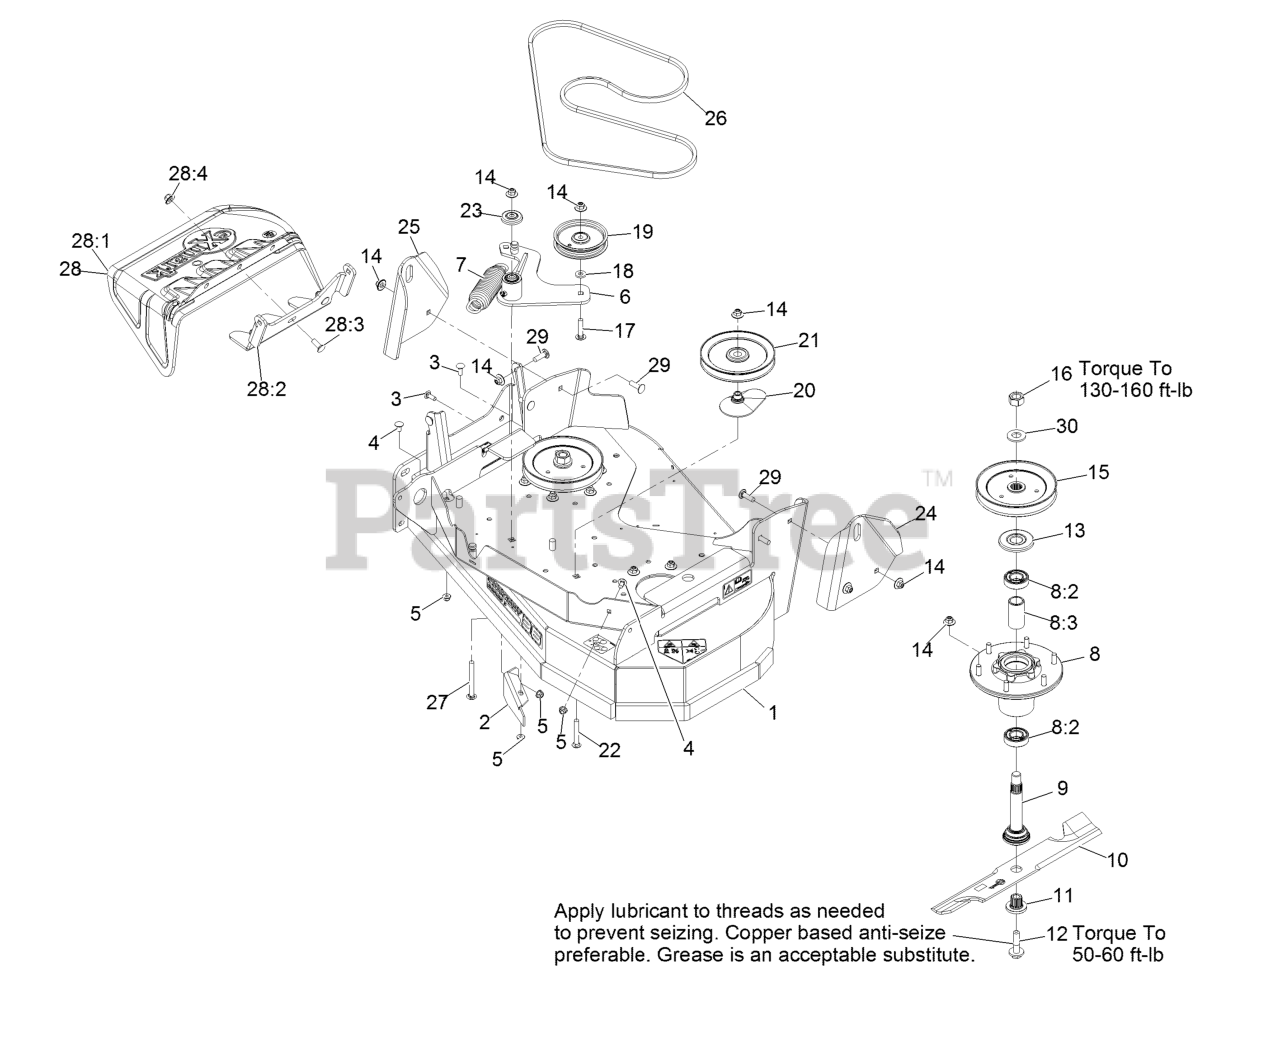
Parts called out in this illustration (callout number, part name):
1	Deck ASM - 36
2	Baffle-Dogleg
3	Bolt-Carriage 5/16-18 X 7/8
4	Bolt-Carriage 5/16-18 X 5/8
5	Nut-Nyloc 5/16-18 Flg
6	Idler Arm ASM -
7	Spring-Extension
8	ASM-Cutter Hsg With Bearings
8:2	Bearing-Ball
8:3	Spacer-Bearing
9	ASM-Spindle And Seal
10	Blade-Notched
10	Blade, Extreme
10	Blade, Mulching
10	Blade, Low Lift
10	Blade, Solid
11	Bushing, Splined
12	Screw-Sems 1/2-20 X 2.19
13	Guard,Bearing Top .989
14	Nut-Nyloc 3/8-16 Flg
15	Sheave,Blade Drive 6.50
16	Nut-Hex
17	Bolt-Carriage 3/8-16 X 1 3/4
19	Pulley-Idler
20	Spacer-Pulley
21	Pulley-Idler
22	Bolt-Carriage 3/8-16 X 2 1/2
23	Guard-Top
24	Push-Tower,LH 36
25	Push-Tower,RH 36
26	Belt-V
27	Bolt-Carriage Shoulder 3/8-16 X 3 1/2
28	Chute - Discharge ASM
28:1	Chute, Discharge
28:2	Bracket-Chute, Discharge
28:3	Bolt-Carriage 3/8-16 X 1
28:4	Nut-Nyloc 3/8-16 Flg
29	Bolt-Carriage 3/8-16 X 1 1/4
30	Washer-Spring Disc 3/4
